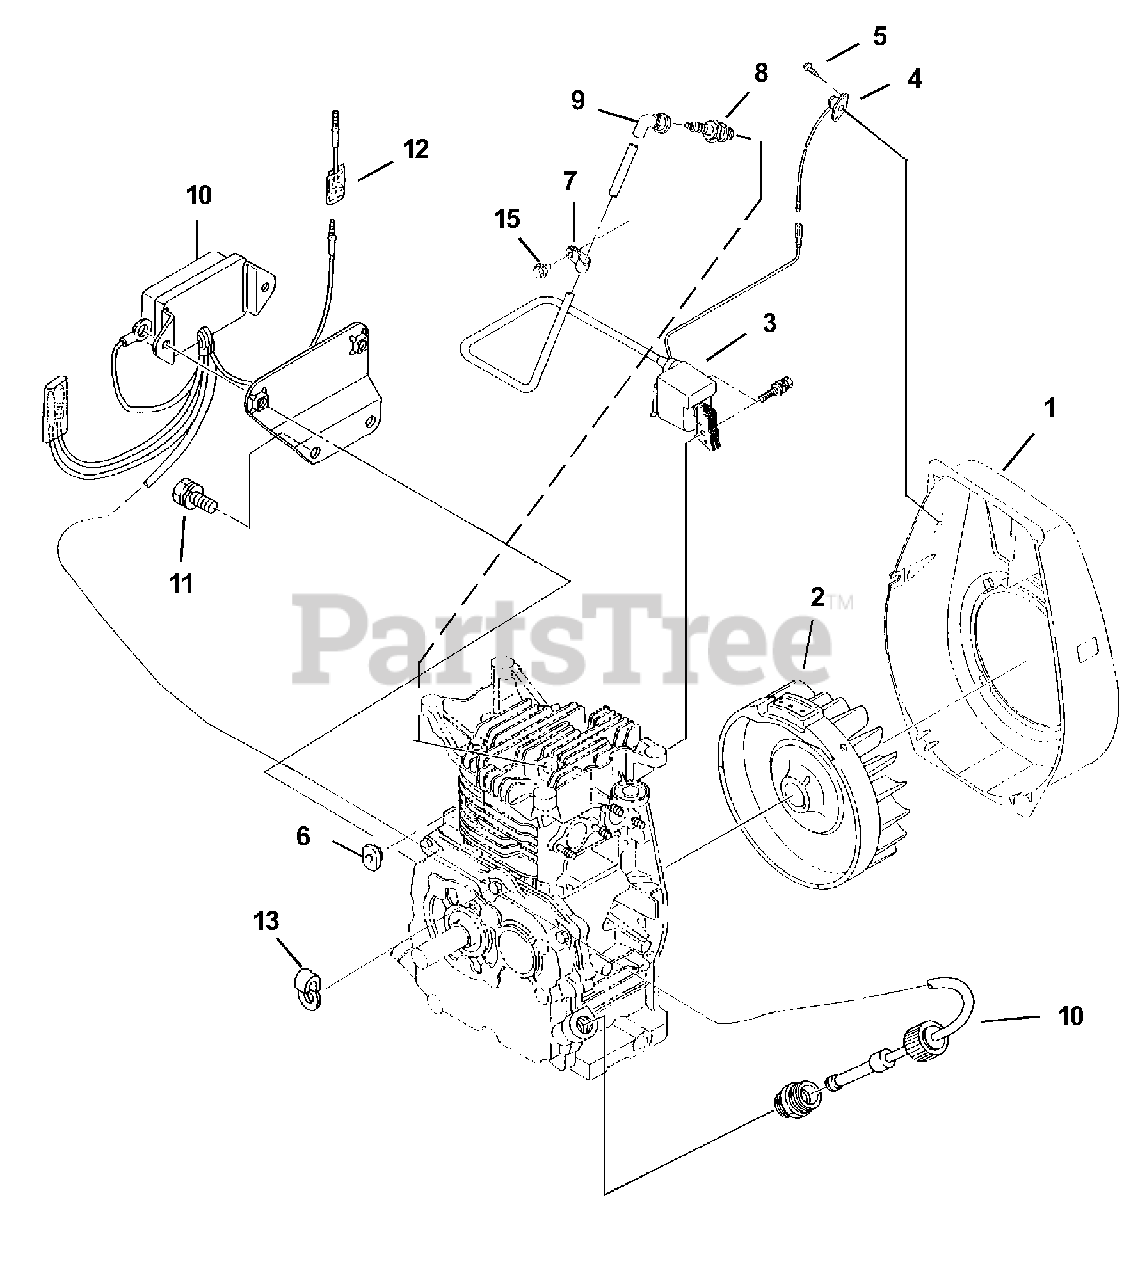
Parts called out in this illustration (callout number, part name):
1	Blower housing
2	Flywheel
3	Ignition coil
5	Tapping screw (M4 X 0.7 X 8L)
8	Spark plug
9	Spark plug cap
10	Oil sensor
11	Bolt & Washer (M8 X 1.25 X 16L)
15	Flange Bolt
